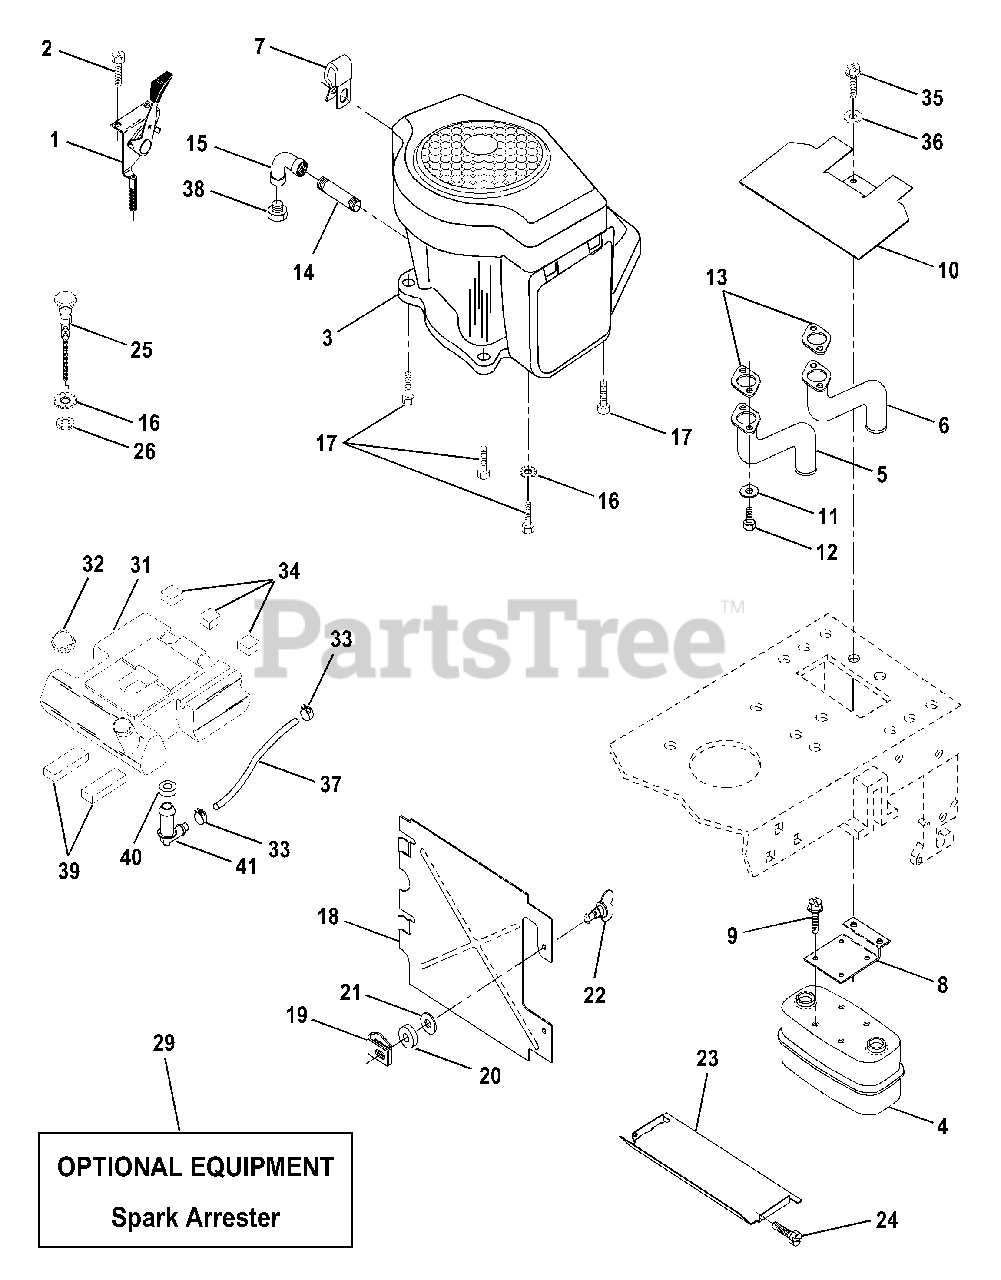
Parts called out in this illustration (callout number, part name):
1	Control RH Blk Flg 37 88
2	Screw Hex Thd Cut 1/4-20x5/8 T
4	Muffler VGT YT Dual Inlet
5	Tube Manifold LH
6	Tube Manifold RH
7	Clip, Fuel Line
8	Bracket Muffler Mounting
9	Screw Hex Wsh Thd Cut 1/4-20
10	Shield Heat LT
11	Washer Lock Hvy Spr 5/16-18
12	Screw Hex Skt 5/16-18 unc x 3/4
13	Muffler Gasket
14	Nipple Pipe 3/8 Npt X 4-1/2"
15	Elbow Std 90 Degree 3/8-18 Npt
16	Washer Lock Ext Tooth 3/8
17	Screw Thdrol 3/8-16 x 1-1/2
18	Shield Heat Mech
19	Receptacle 1/4 Turn
20	Retainer 1/4 Turn
21	Bushing, Snap, Split Blk
22	Stud 1/4 Turn
23	Shield Heat Browning LT/YT
24	Screw Tap Hex #10-24unc X 1/2
25	Choke Control
26	Nut, Fin Hex 3/8-24 Unf
29	Kit Spark Arrestor (Flat Scrn)
31	Tank Fuel 3 50 Rear
32	Cap Asm Fuel
33	Clamp Hose Blk
34	Pad, Spacer
35	Screw Thdrol 5/16-18 x 3/4
36	Washer 13/32 x 1-1/4 x 12 Ga.
37	Line Fuel 54"
38	Plug Oil Drain
39	Pad, Idler
40	Bushing
41	Stem Tank Fuel
